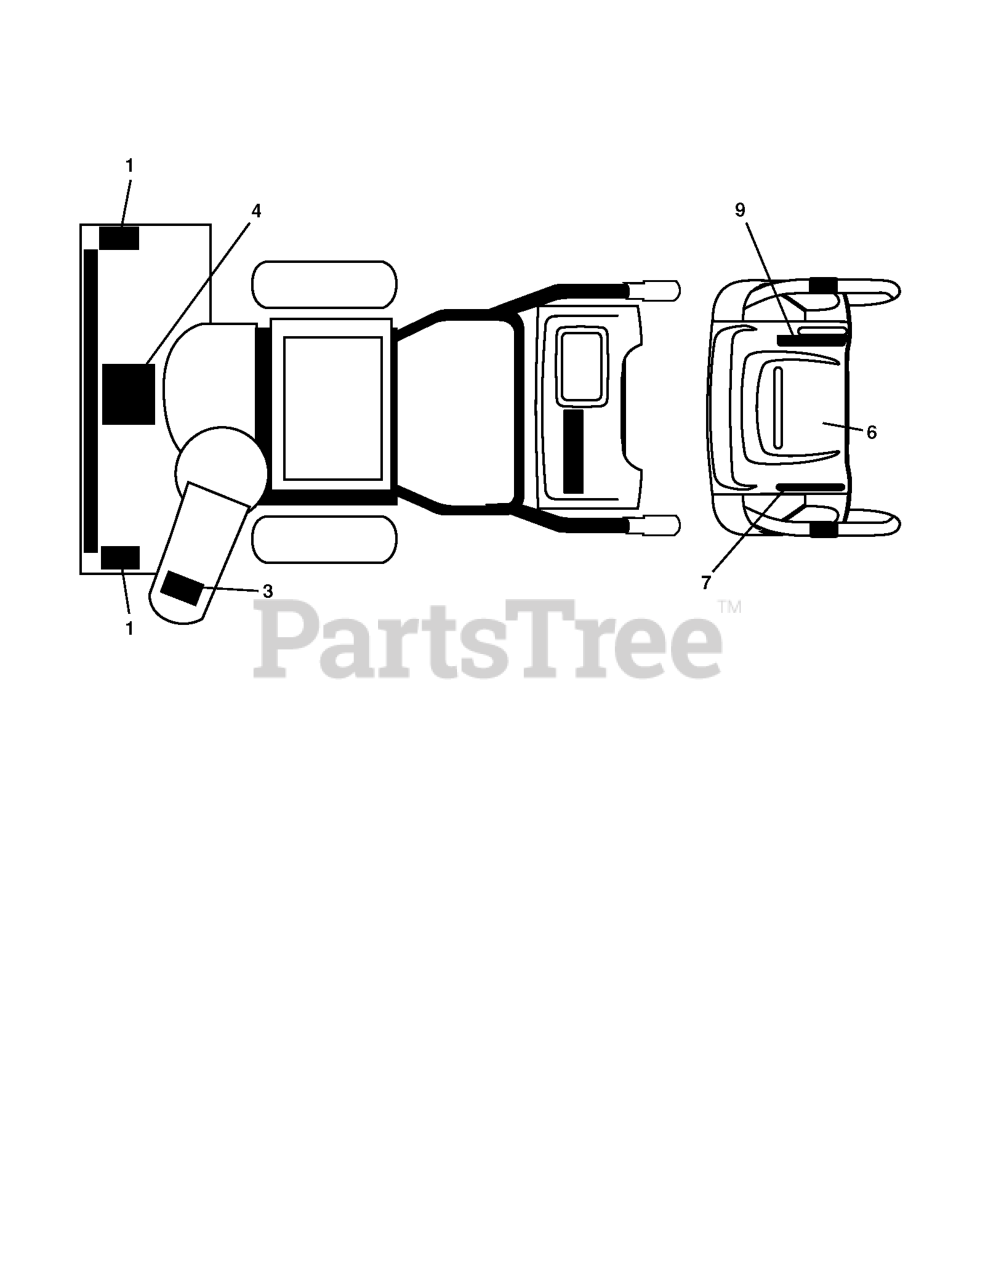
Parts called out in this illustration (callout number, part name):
1	DECAL.SNOWTHR.AUGER
3	DECAL.SNOWTHR.CHUTE.SAFETY
4	DECAL.SNOWTR.READ.OWN.MAN.E/F
6	DECAL.CONSOLE.SNOW.INST.ENG/FR
7	DECAL.CONS.LT.WO/DEFL.GRY
9	DECAL.CONS.RT.SPD/LEV/PWRST.
